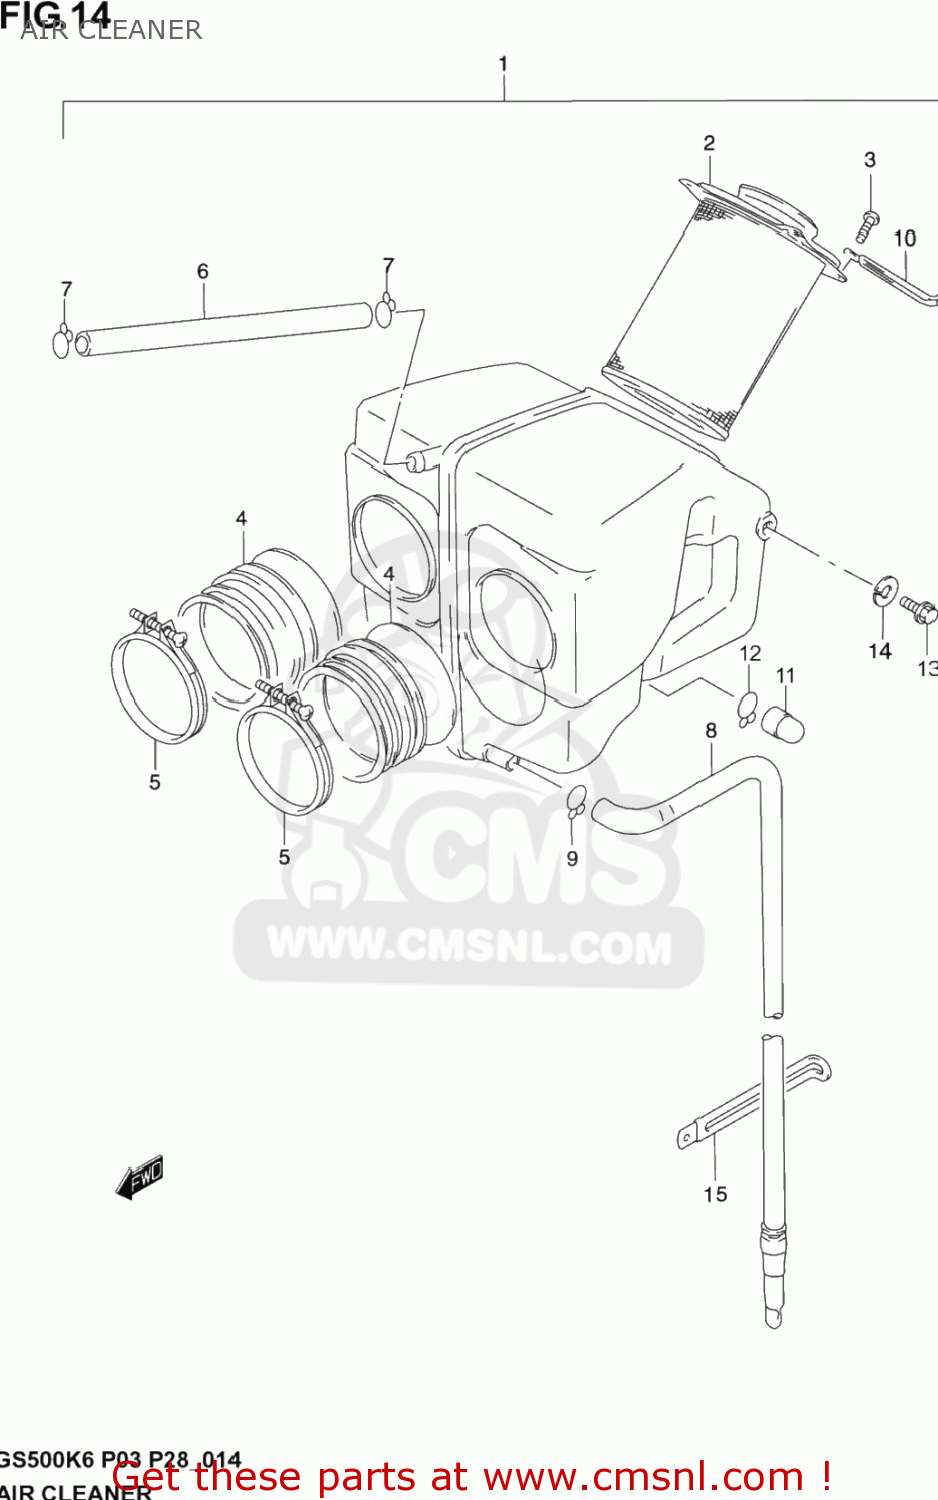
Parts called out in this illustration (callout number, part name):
1	CLEANER ASSY,AIR
2	FILTER ASSY
3	SCREW
4	TUBE,OUTLET
5	CLAMP
6	HOSE(11X15X600)
7	CLIP
8	TUBE,DRAIN
9	CLIP
10	CLAMP(L:65)
11	PLUG
12	CLIP
13	BOLT
14	WASHER
15	CLAMP(L:80)
